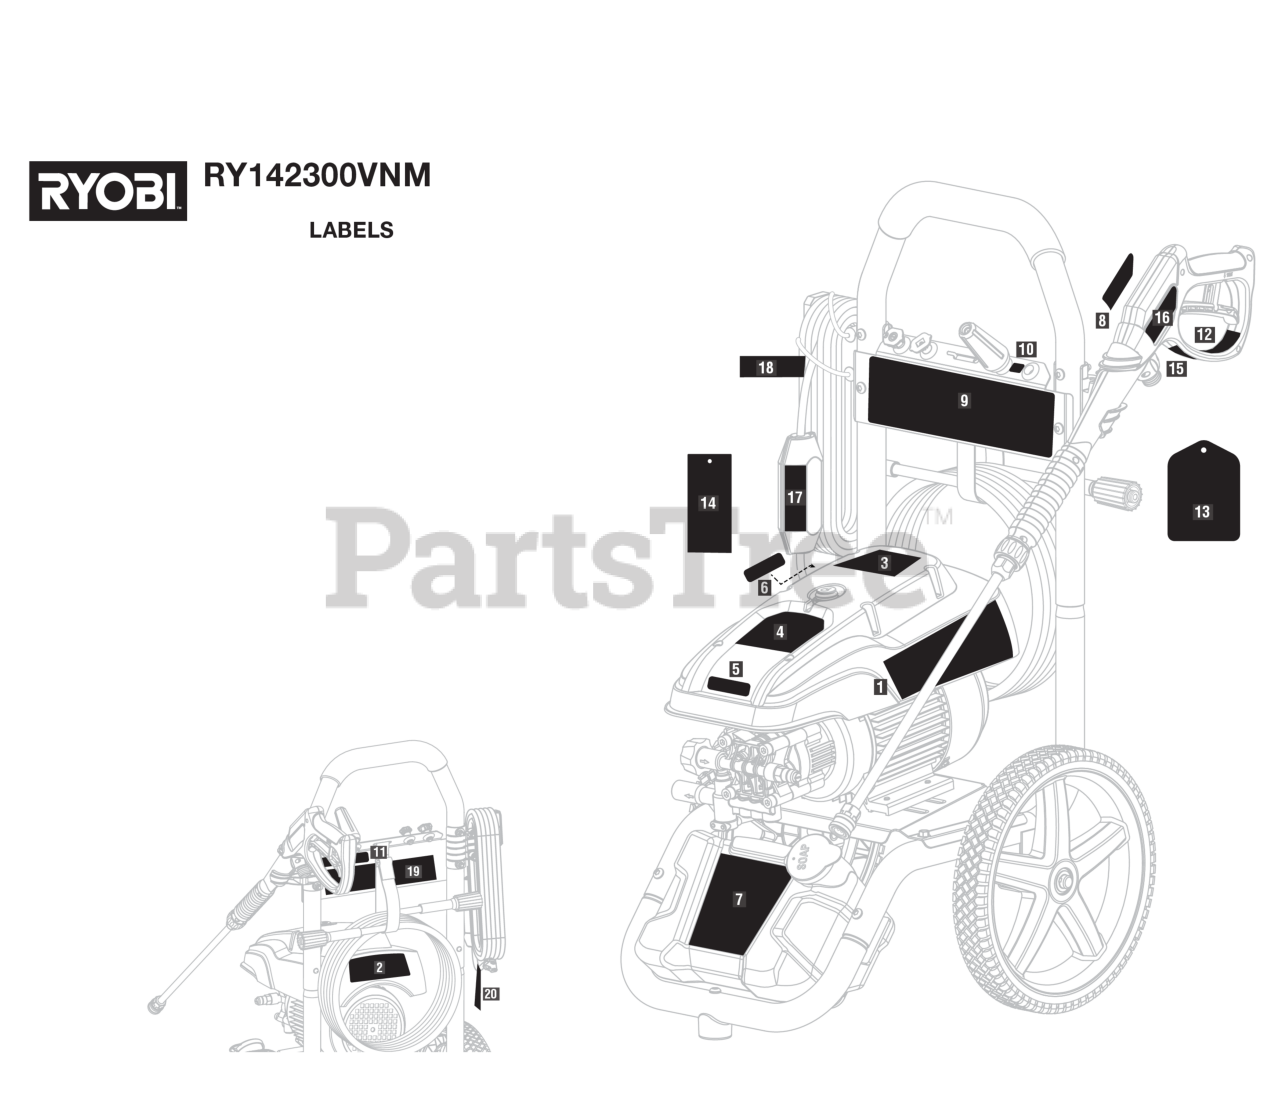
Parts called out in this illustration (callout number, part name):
1	Danger Label
2	Regulatory Danger Label
3	High Performance Motor
4	On/Off/Brushless Label
5	Logo Label
6	Try Another Outlet Label
7	Detergent Tank Label
8	Clutch Cover Label
9	Performance Label
10	Nozzle Storage Label
11	Inquires Label (Ryobi)
12	Label (Trigger Handle Warning, French & Spanish)
13	Nozzle Hangtag (PS141913)
14	Danger Hangtag (Spanish)
15	Rating Label
16	Trigger Handle Warning Label (English)
17	Power Cord Label
18	Cordwrap Warning Label
19	Quick Start Label
20	Outlet Cord Wrap Label
